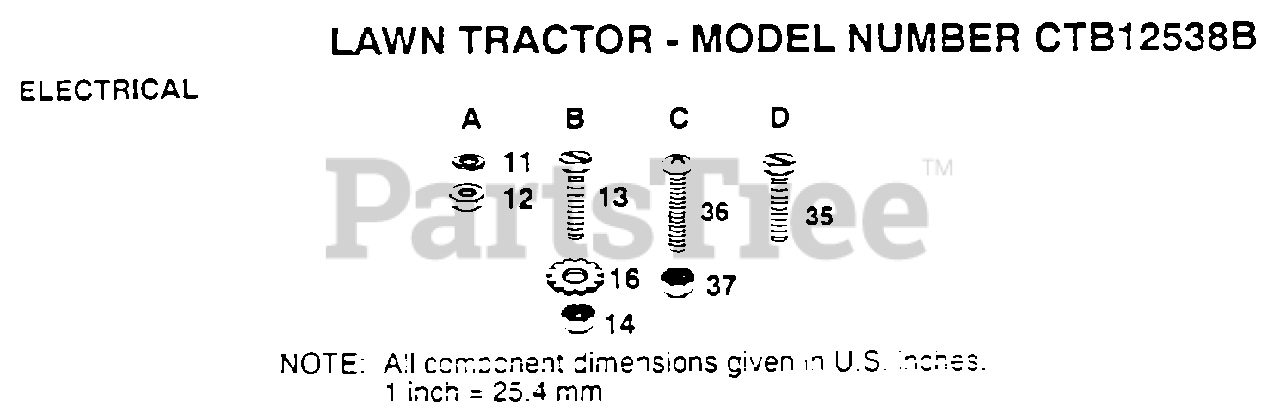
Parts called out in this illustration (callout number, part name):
12	NUT
13	BOLT
14	NUT
35	SCREW
37	"NUT,KEPS"
